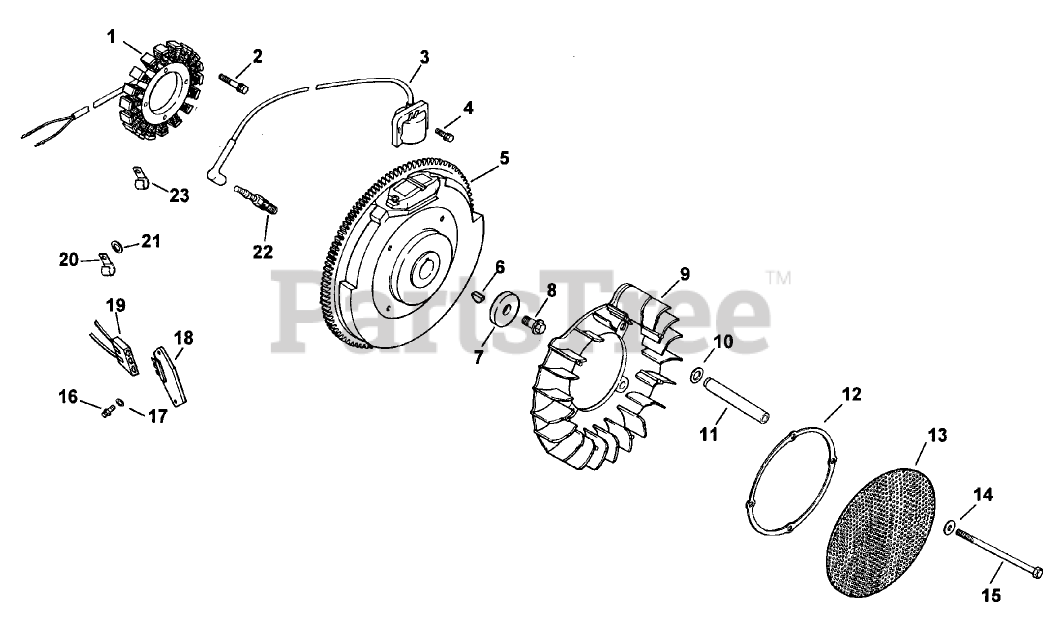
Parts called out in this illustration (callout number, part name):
1	Stator-15 amp
2	Screw
3	Module-Ignition
5	Flywheel
6	Key
7	Washer
8	Screw
9	Fan
10	Washer, sping
11	Spacer
12	Ring-Support
13	Screen-Grass
14	Washer
15	Screw-Hex
16	Screw
17	Washer
18	Rectifier-Regulator
19	Connector
20	Clip
21	Washer
22	Plug-Spark
23	Clip
